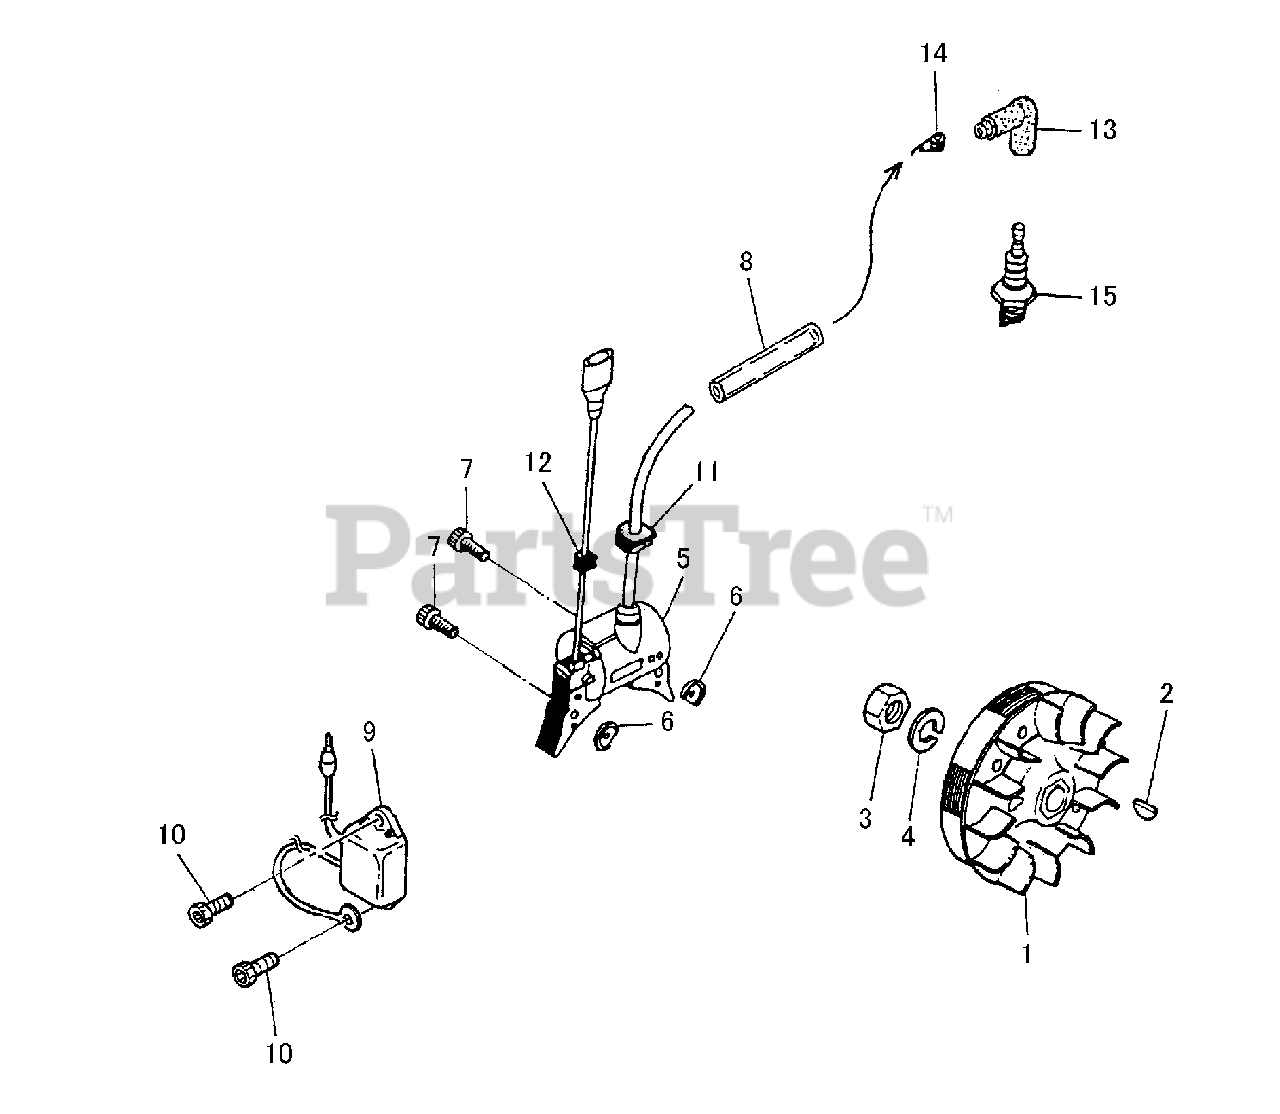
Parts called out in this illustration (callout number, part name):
1	FLYWHEEL
2	KEY, WOODRUFF 3×10
3	NUT 10×1.25
4	WASHER, SPRING 10
5	COIL, IGNITION
6	COLLAR 4
7	BOLT M4×26
8	TUBE, INSULATOR
9	ELECTRONIC UNIT
10	BOLT M4×12
11	GROMMET
12	GROMMET, LEAD
13	CAP, SPARK PLUG
14	TERMINAL, SPARK PLUG
15	SPARK PLUG - CJ8
